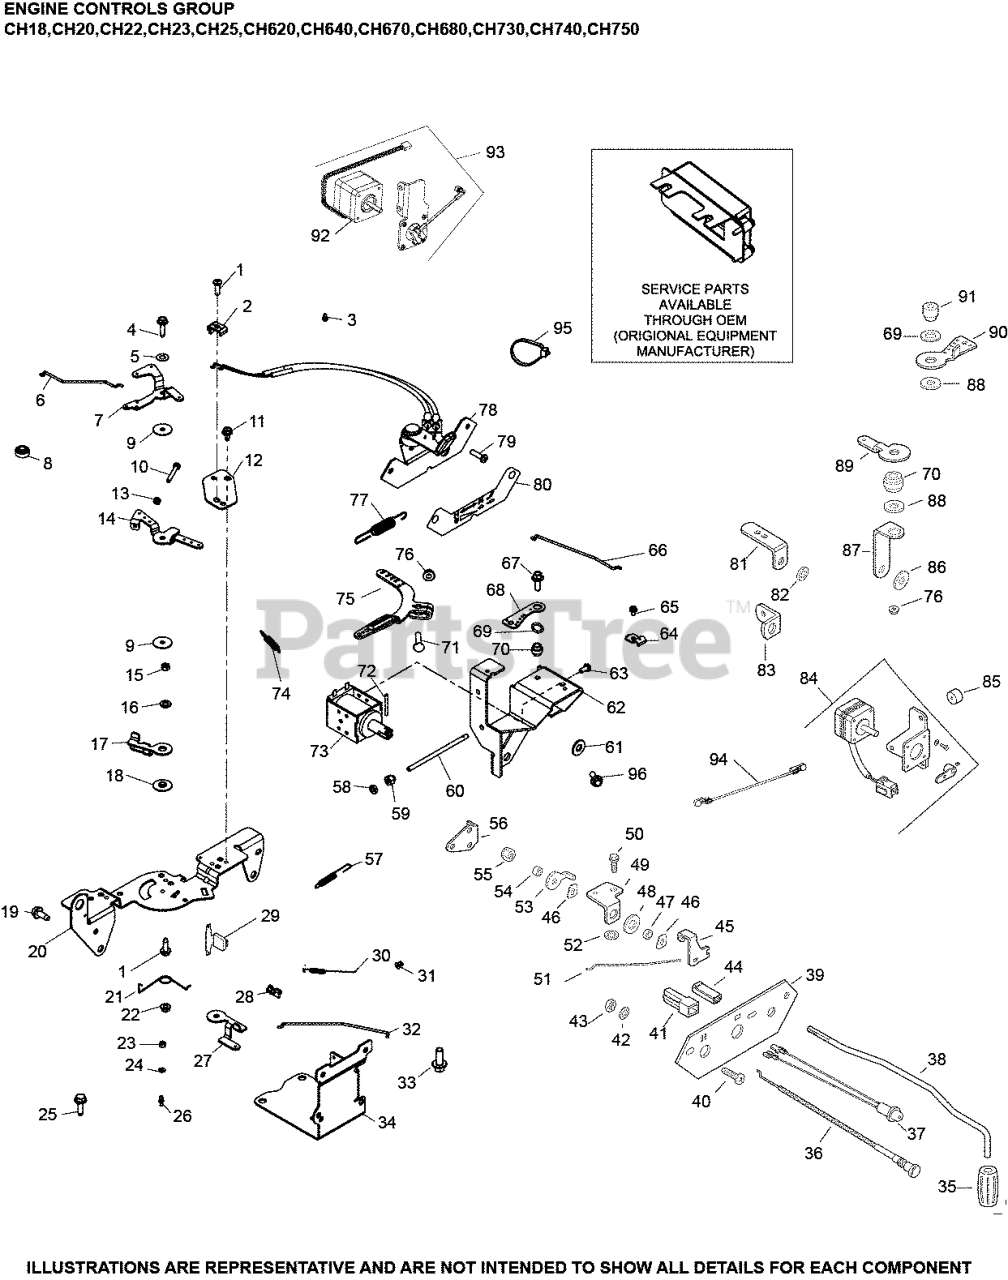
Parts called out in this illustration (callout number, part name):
1	SCREW, THREAD FORMING
2	CLAMP, CABLE
4	SCREW, THREAD FORMING - USE 25 086 473-S
5	WASHER, SPRING 1/4"
6	LINKAGE, CHOKE
7	LEVER, CHOKE
9	WASHER, FLAT 5.5 MM
10	SCREW, CAP M4X.7X30
13	NUT, M4X0.7
14	LEVER, THROTTLE CONTROL
15	NUT, FLG M5X.8
16	WASHER, SPRING LOCK 1/4"
19	SCREW, THREAD FORMING
20	BRACKET, CONTROL
21	SPRING, CHOKE RETURN
22	NUT, LOCK M5X.8
27	LEVER, THROTTLE ACTUATOR
28	BUSHING, THROTTLE LINKAGE
30	SPRING, LINKAGE
31	BUSHING, LINKAGE RETAINING
57	SPRING, THROTTLE LIMITER
66	LINKAGE, THROTTLE
71	BOLT, RD HD SQ NECK M6X1.0X25
75	LEVER, GOVERNOR ASSEMBLY
76	NUT, FLG M6X1.0
77	SPRING, GOVERNOR (BLACK)
